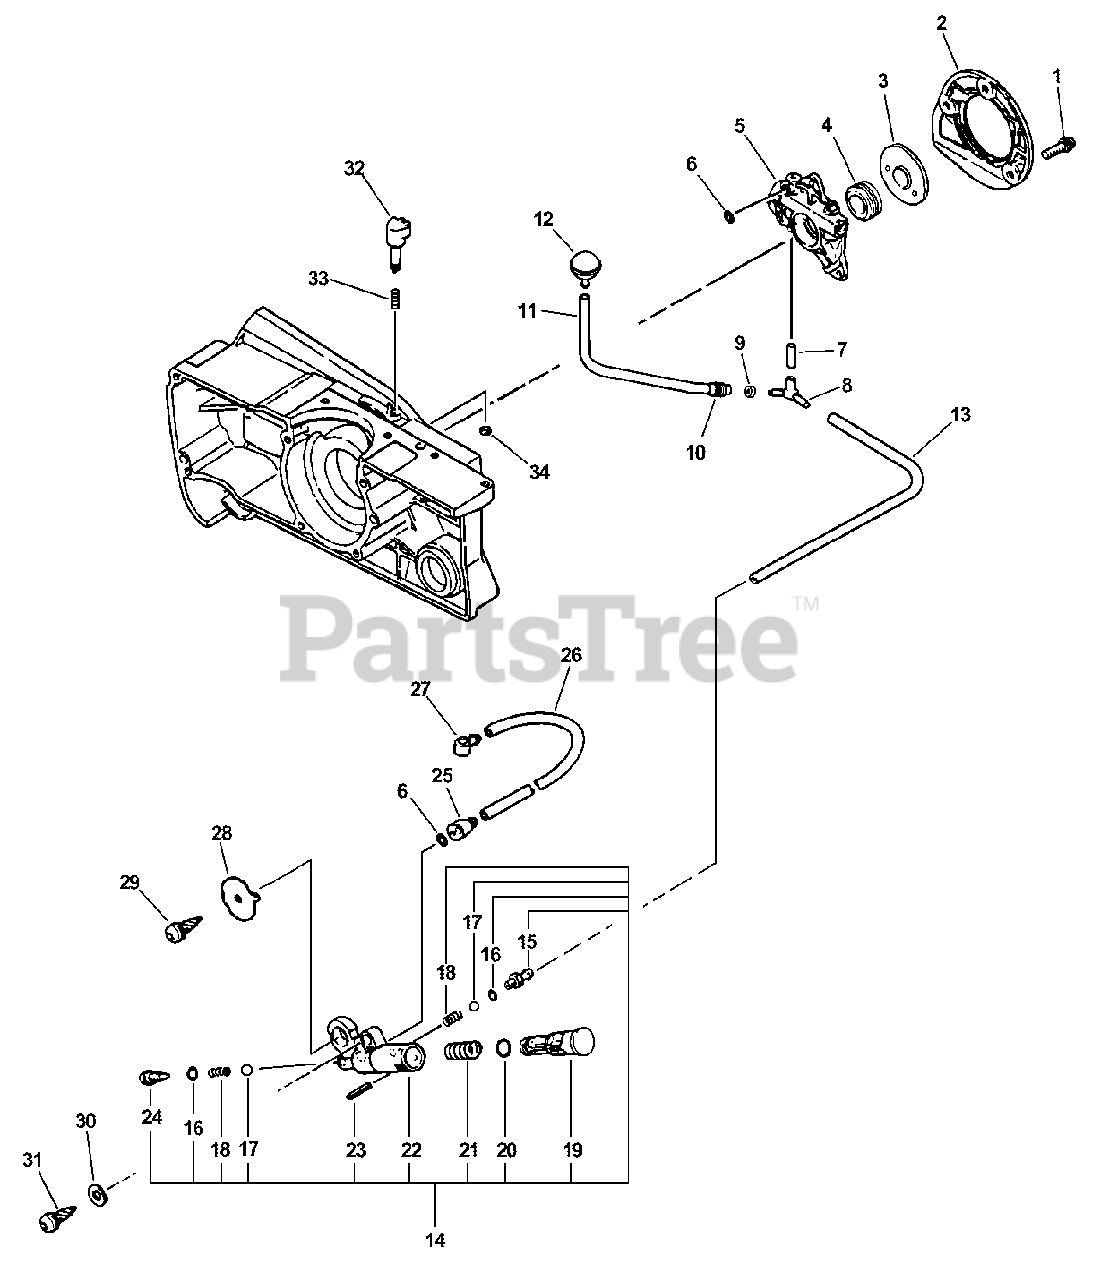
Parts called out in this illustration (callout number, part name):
1	BOLT 4×12
2	COVER, OIL PUMP - GRAY
3	WASHER 12
4	GEAR, WORM
5	AUTO-OILER ASSY
6	O-RING 3
7	PIPE, OIL 3×6×20
8	CONNECTOR, PIPE
9	CLIP Ø6.5 MM
11	PIPE, OIL
12	FILTER, OIL
13	PIPE, FUEL 3×6×200
14	OIL PUMP ASSY
15	CONNECTOR, PIPE
17	VALVE, BALL
18	SPRING, COMPRESSION
19	PISTON, OIL PUMP - ORANGE
20	O-RING 7 MM
22	BODY, OIL PUMP
23	PIN, SPRING 2×16
24	ADAPTOR, OIL PUMP
25	CONNECTOR, PIPE
26	PIPE 3×6×125 BLACK
27	CONNECTOR, PIPE
28	BRACKET, OIL PUMP
29	SCREW 4×10
30	WASHER 5.5×12×0.8
31	SCREW 5×20
34	E-RING 3
